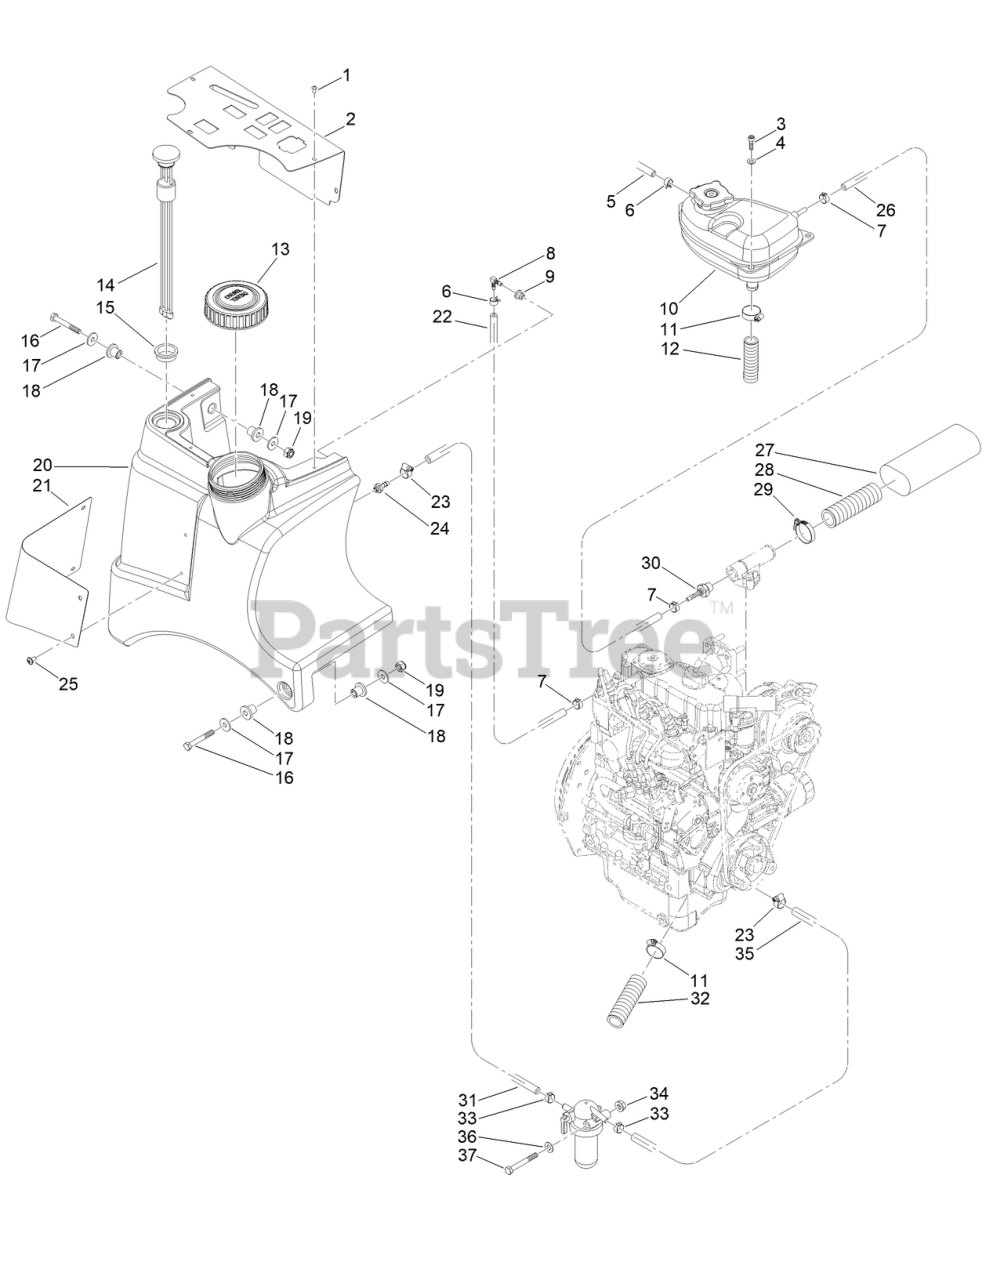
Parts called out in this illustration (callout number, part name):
1	SCREW-H-SCKT B HEAD CAP
2	DASHBOARD, LH
4	WASHER
8	FITTING, 90 DEG
9	GASKET, FITTING WS5
10	WATER EXPANSION TANK
12	HOSE, RADIATOR
13	CAP-TANK, DIESEL
14	FUEL GAUGE
15	GASKET, FUEL GAUGE
17	WASHER
18	BUSHING
20	FUEL TANK
21	COVER, FUEL TANK
23	CLIP-WORM
24	FITTING,
27	HOSE GUARD
28	HOSE, RADIATOR 25X1240
30	FITTING-TAPER
31	HOSE-RUBBER
32	HOSE, RADIATOR
36	WASHER
